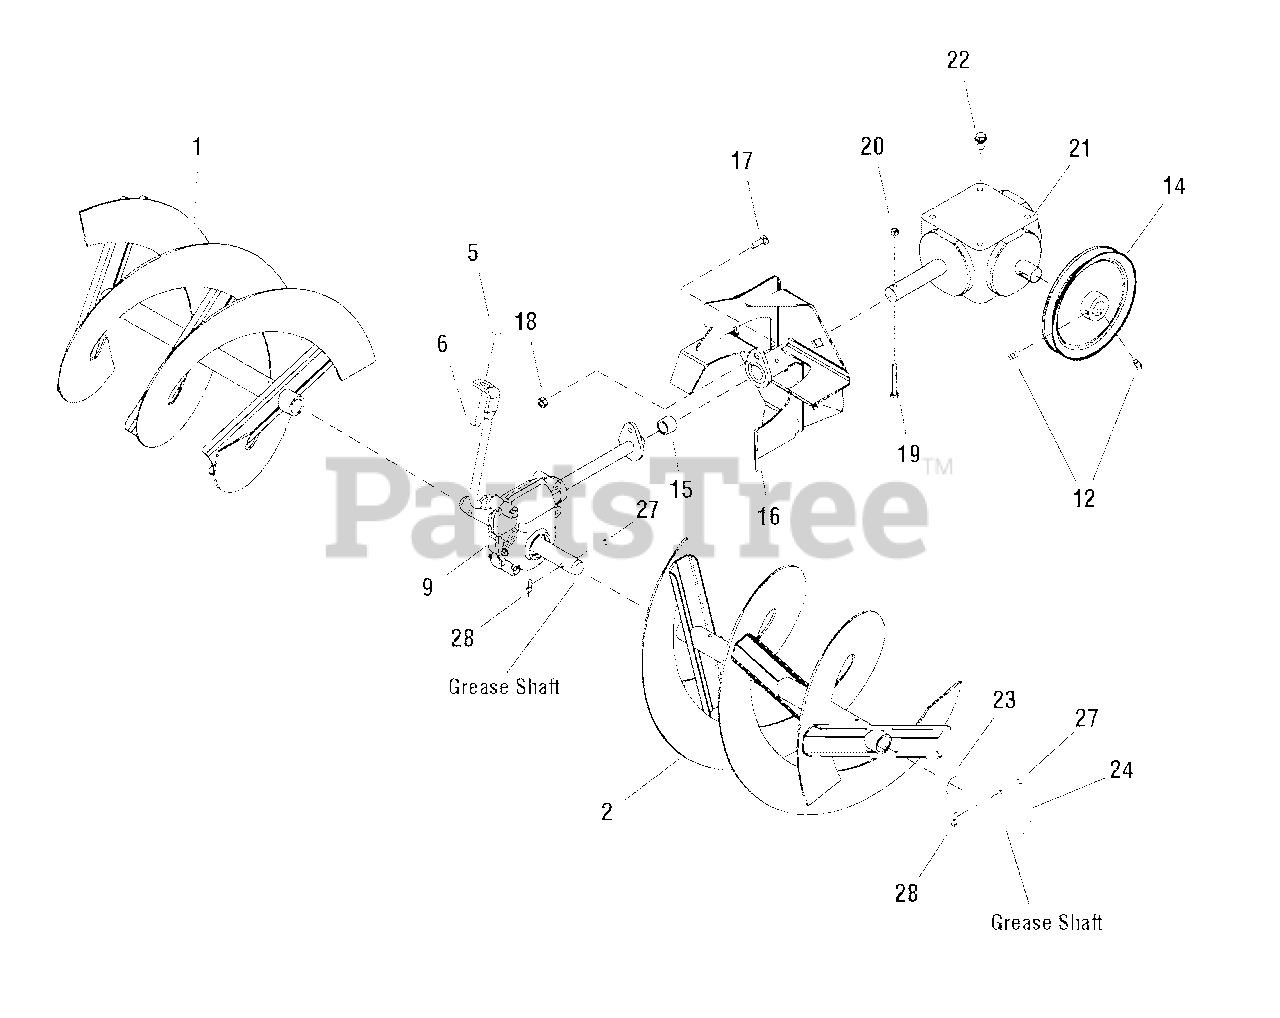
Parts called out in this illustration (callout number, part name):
1	AUGER ASSEMBLY, 42" Housing, R.H.
2	AUGER ASSEMBLY, 42" Housing, L.H.
5	CARRIAGE BOLT, 5/16-18 x 3/4, G5
6	NUT, Hex Whiz Lock Flange, 5/16-18
9	AUGER, Gearbox Assembly
12	SET SCREW, Square Head Cup 5/16-18 x 1/2, G8
14	PULLEY, 7.50 OD
16	IMPELLER ASSEMBLY, Large Frame Snow
17	CARRIAGE BOLT, 5/16-18 x 1
18	NUT, Hex, Nylock 5/16 - 18
19	CAPSCREW, 1/4 - 20 x 7/8
20	NUT, Hex, Nylock 1/4 - 20
21	GEARBOX, Assembly, Black
22	CAPSCREW, Whiz, 3/8 - 16 x 3/4
23	BUSHING, 1.009ID x 1-1/8 OD x 1.13 Long Zytel
24	SHAFT, 0.98 Diameter 4.85 Long
27	PIN, Shear, .248 ID x 1-3/4 Long
28	COTTER PIN, 1/4" Self Locking
